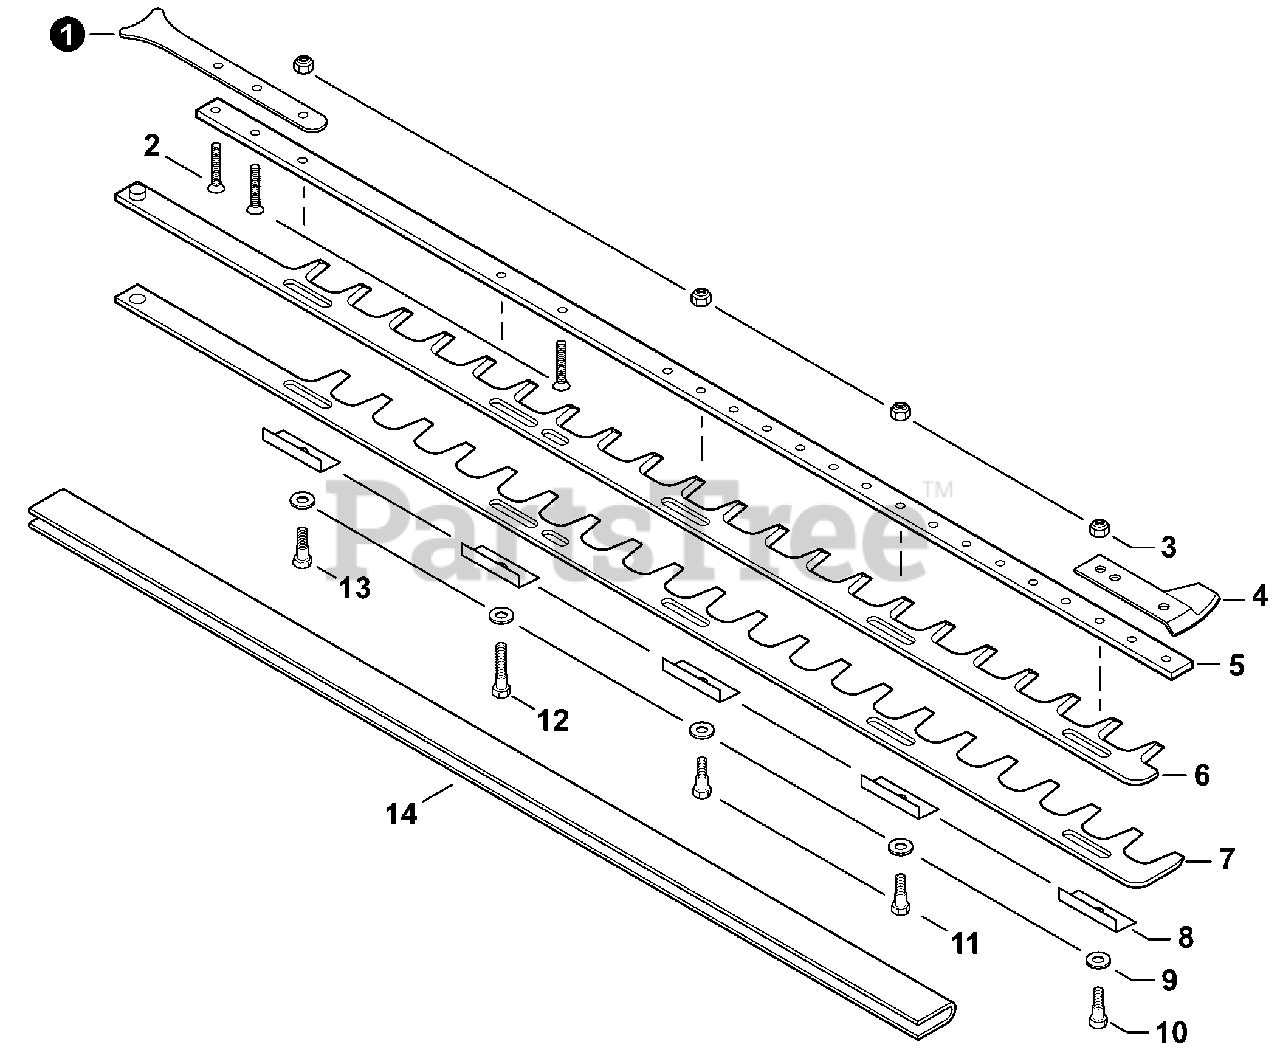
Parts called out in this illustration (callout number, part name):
1	PLATE, EYE
2	BOLT 6×30
4	GUARD, TIP
5	SUPPORT, BLADE 30"
6	BLADE, UPPER 30"
7	BLADE, LOWER 30"
8	GUIDE, BLADE
10	BOLT 6×24
11	BOLT 6×22
12	BOLT 6×40
13	BOLT 6×25
14	SCABBARD
